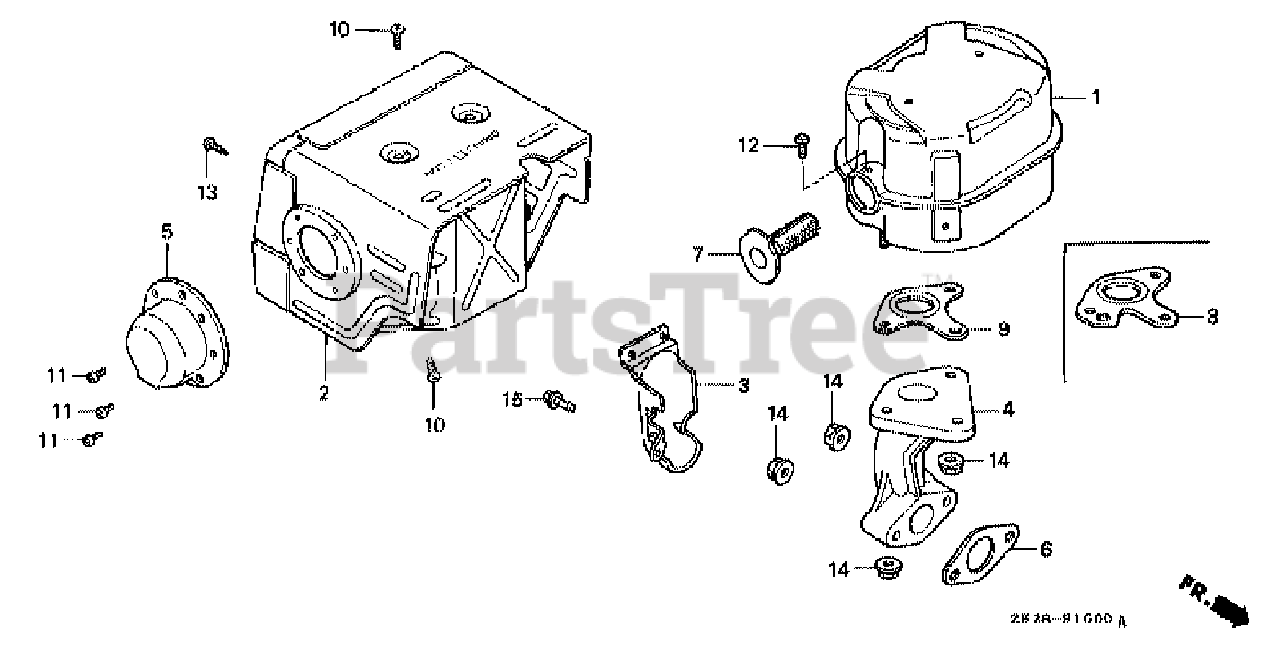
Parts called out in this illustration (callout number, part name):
1	MUFFLER
2	PROTECTOR, MUFFLER
3	PROTECTOR, EX. PIPE
4	PIPE, EX.
5	CAP, MUFFLER
6	GASKET, EX. PIPE
6	GASKET, EX. PIPE (WACKER)
7	ARRESTER, SPARK
8	GASKET, MUFFLER (ARRESTER)
10	SCREW, TAPPING (5X8)
11	SCREW, TAPPING (4X6)
12	SCREW, TAPPING (4X6)
14	NUT, FLANGE (8MM)
15	BOLT, FLANGE (6X12) (CT200)
